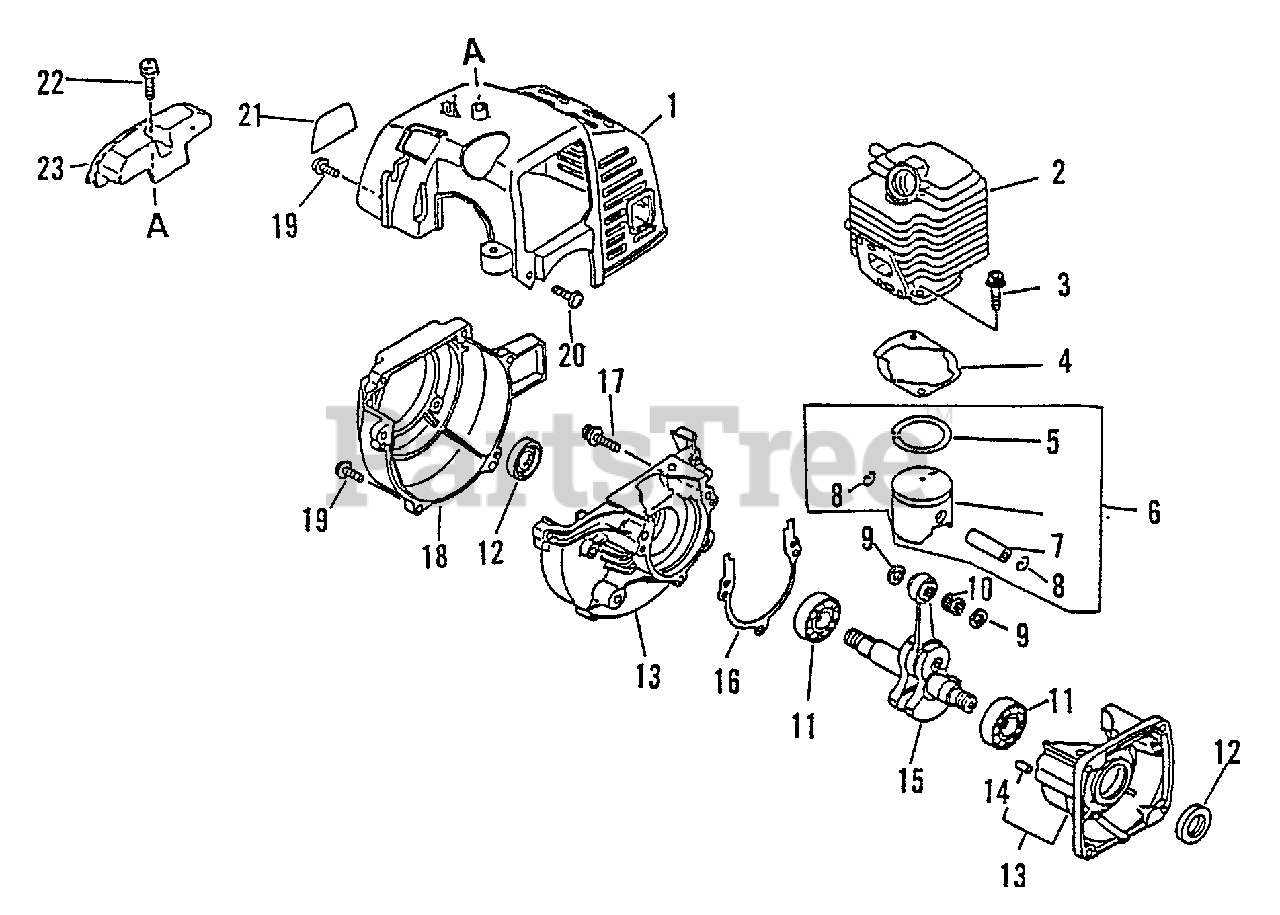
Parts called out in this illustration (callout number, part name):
1	COVER, ENGINE - GRAY
2	CYLINDER
3	SCREW - 5X22
4	GASKET, CYLINDER
5	RING, PISTON
6	PISTON KIT
7	PIN, PISTON
8	RING, RETAINING
9	SPACER, PISTON
10	BEARING, NEEDLE
11	BEARING, BALL - 6201
12	SEAL, OIL
13	CRANKCASE KIT
14	PIN - LOCATING
15	CRANKSHAFT ASSY
16	GASKET, CRANKCASE
17	SCREW - 5X28
18	CASE, FAN - GRAY
19	SCREW - 4X16
20	SCREW - 4X12
21	LABEL - MODEL 2310
22	SCREW - 5X16 -- TAPPING
23	GUARD, TOP - BLACK
